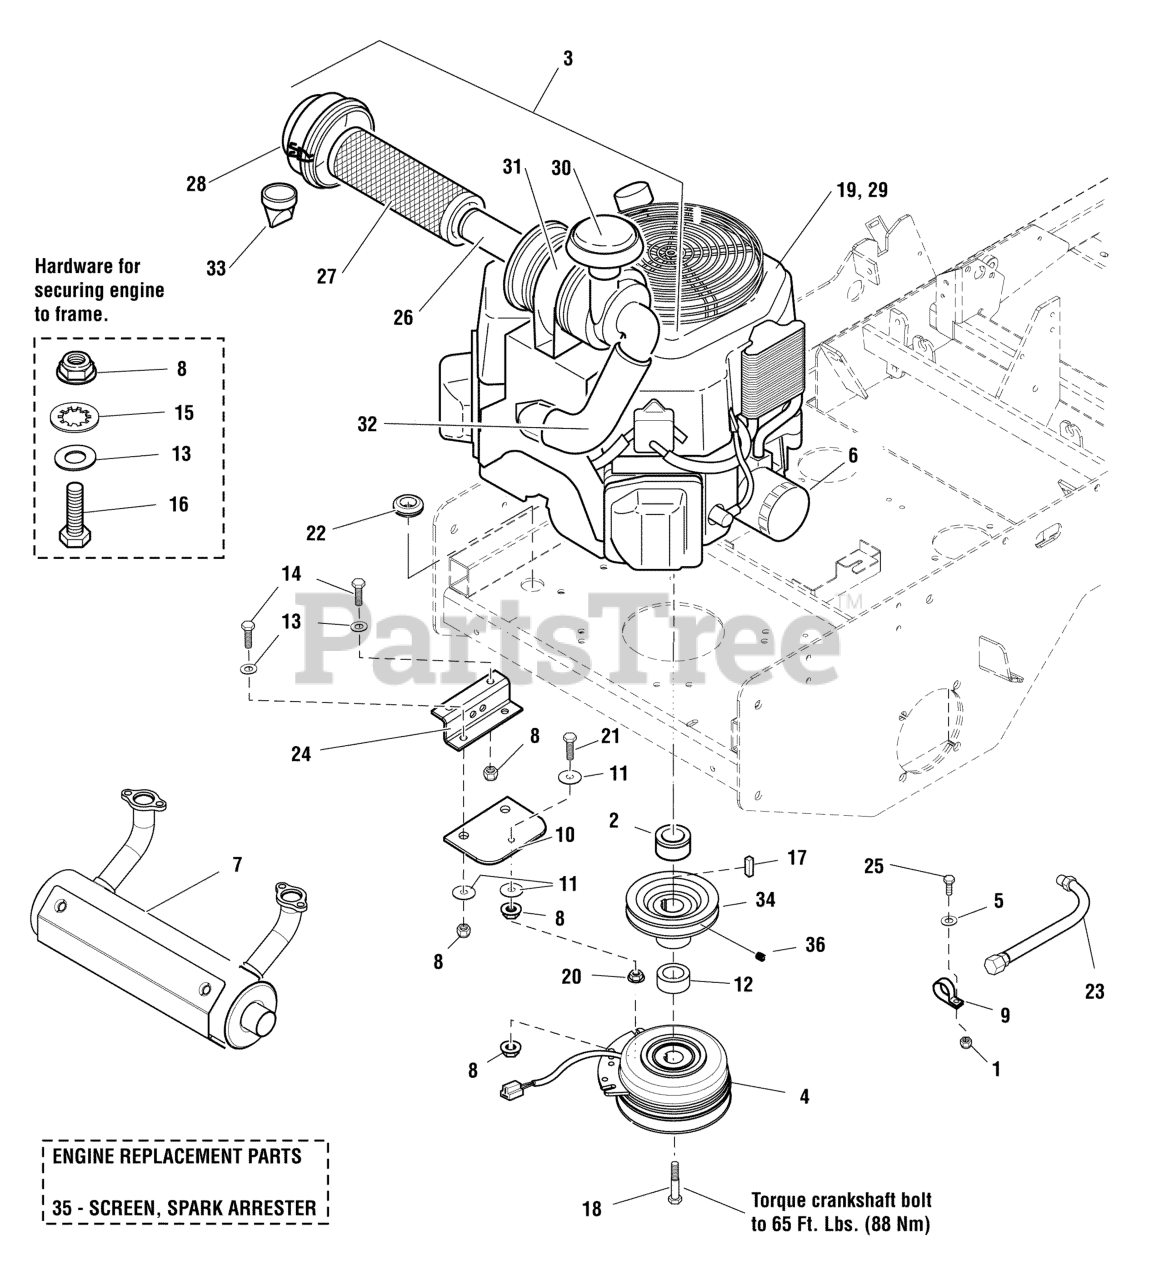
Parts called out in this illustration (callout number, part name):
1	NUT, 1/4-20 HEX NYLOCK FLANGE
2	SPACER, 1.13 X 1.75 X 1.03
3	KIT, 5.5" HD AIR CLEANER (24 743 22-S) (SV)
4	* CLUTCH, 5218-134, WARNER
5	WASHER, 1/4 SAE
6	OIL FILTER (SV)
7	MUFFLER, KOHLER 21 HP - 27 HP
8	NUT, 5/16-18 HEX NYLOCK FLANGE
9	CLAMP, VINYL INSULATED
10	CLUTCH ANCHOR PAD
11	WASHER, .34 X 1.25 X 10 GA
12	SPACER, 1.13 X 1.75 X .75
13	WASHER, 5/16" SAE
14	BOLT, 5/16-18 X 1 GD5 YZ
15	WASHER, 5/16" INT. TOOTH LOCK
16	BOLT, 5/16-18 X 1-3/4 GD5 YZ
17	KEY, 1/4 SQ X 1
18	BOLT, CRANKSHAFT, 7/16"X2-1/2
19	* ENGINE, 27HP KOHLER
20	NUT, 5/16-18 HEX SERRATED FLANGE (SMALL)
21	BOLT, 5/16-18 X 2-1/4 TFL, GD5 YZ
22	GROMMET, 7/8
23	HOSE, OIL DRAIN
24	ANCHOR, CLUTCH - BLK
25	BOLT, 1/4-20 X 3/4 GD5 YZ
26	AIR FILTER, SECONDARY (SV)
27	AIR FILTER, PRIMARY (SV)
28	END CAP (25 096 06-S) (SV)
29	* ENGINE, 23HP KOHLER
30	RAIN COVER (SV)
31	BRACKET (25 126 02-S) (SV)
32	AIR INLET TUBE (25 326 53-S) (SV)
33	DUST CAP (24 462 07-S) (SV)
34	PULLEY, 5.15 OD X 1-1/8 BORE B-SECT
35	SCREEN, SPARK ARRESTER
36	SET SCREW, 5/16-18 X 3/8, KNURL, W/PATCH
